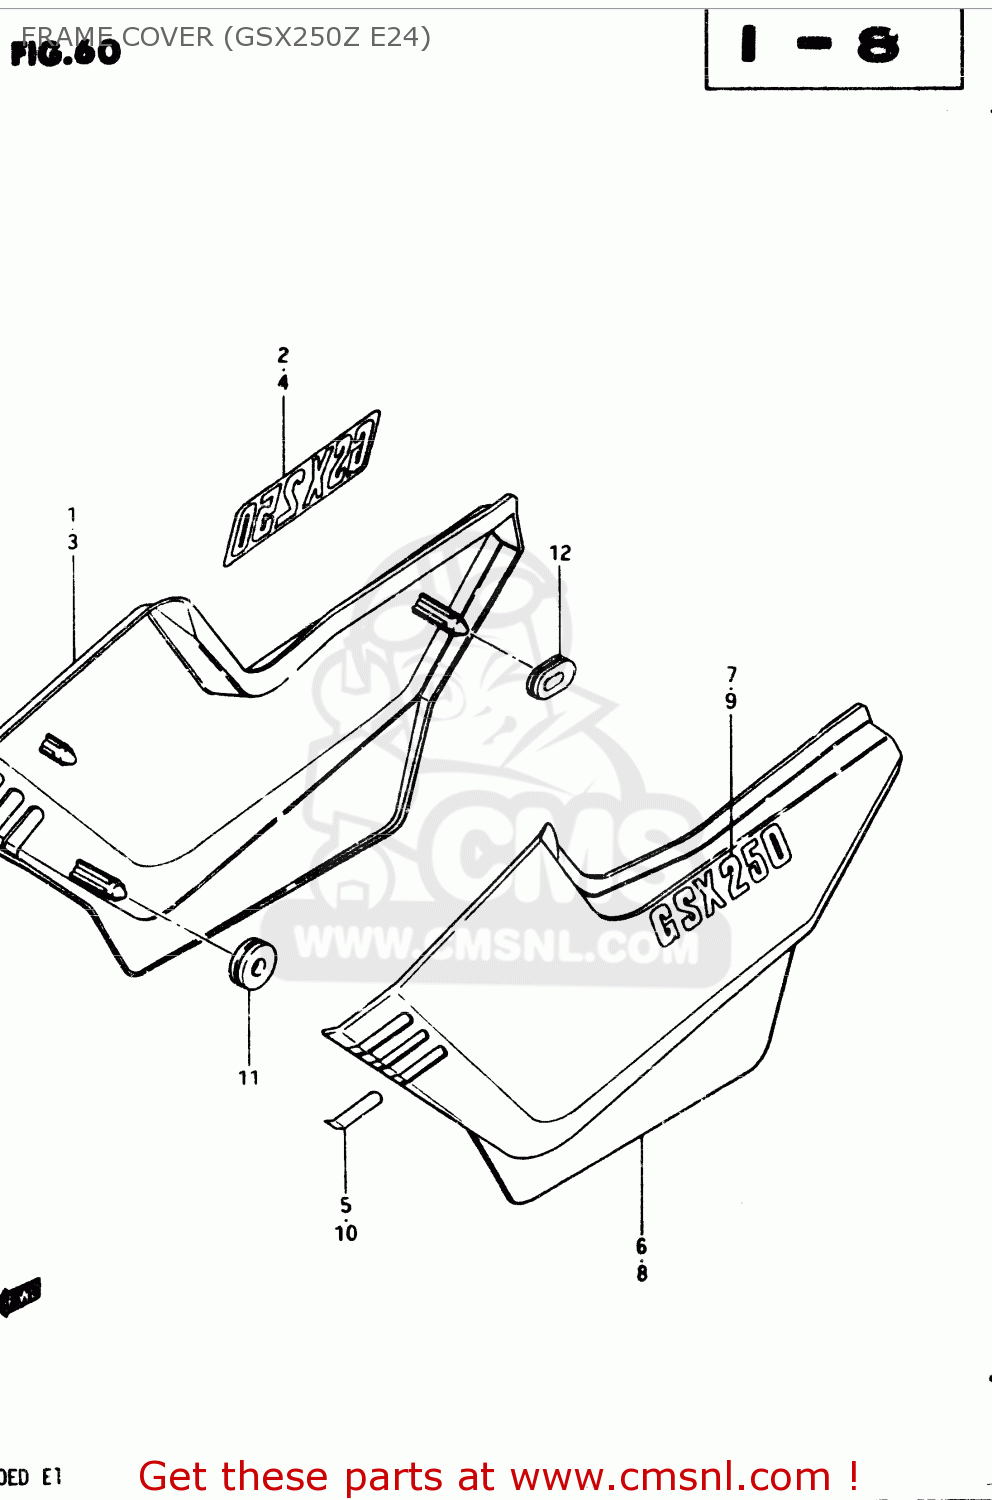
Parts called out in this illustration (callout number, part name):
1	COVER, FRAME RH (RED)
2	EMBLEM, LH (SILVER)
3	COVER, FRAME RH (SILVER)
4	EMBLEM, LH (BLACK)
5	LABEL,FRAME COVER DENT
6	COVER, FRAME LH (RED)
7	EMBLEM, LH (SILVER)
8	COVER, FRAME LH (SILVER)
9	EMBLEM, LH (BLACK)
10	LABEL,FRAME COVER
11	CUSHION
12	CUSHION
